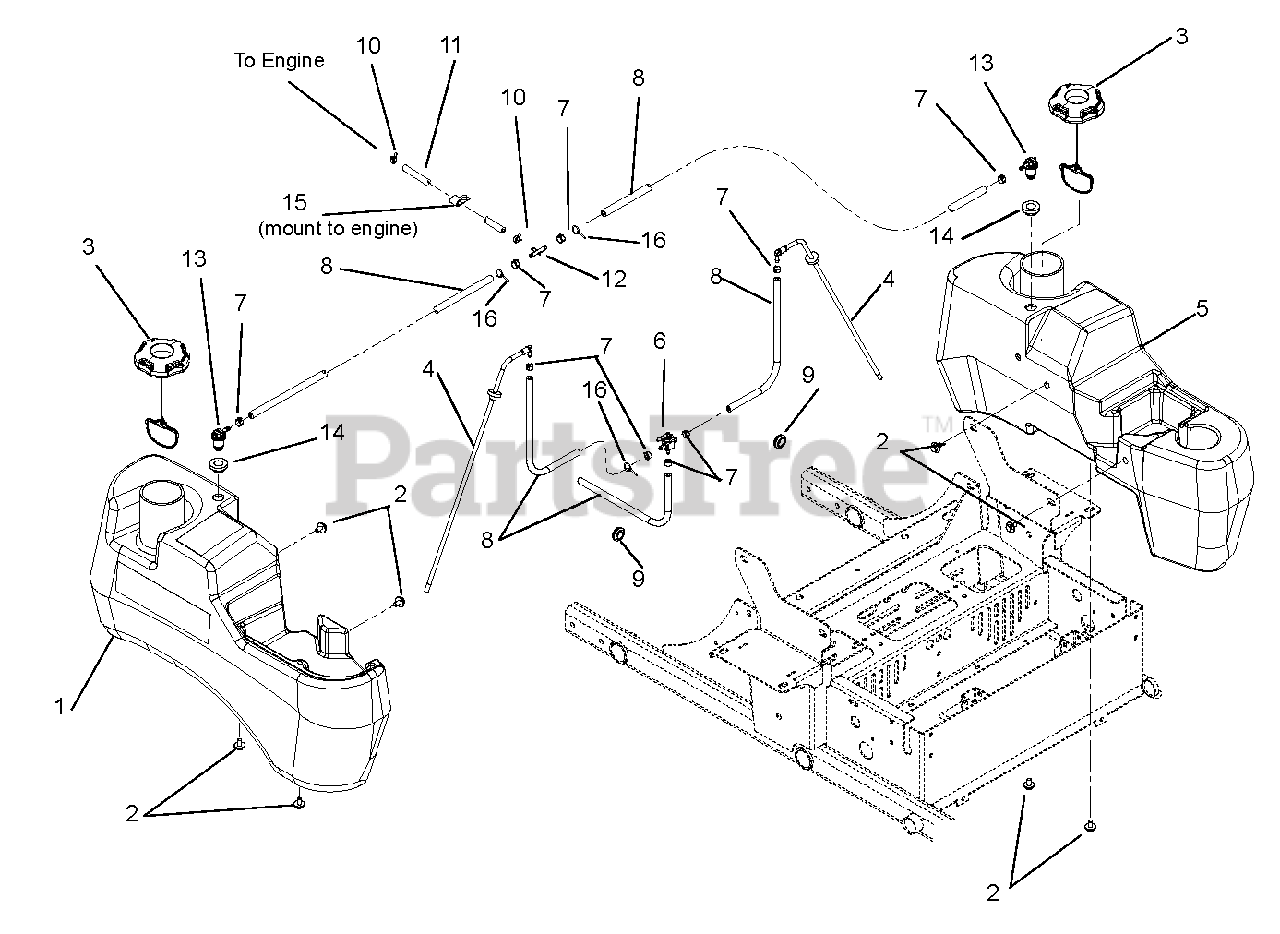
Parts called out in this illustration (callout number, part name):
1	Tank, Right Hand Fuel
2	Bolt, SEMS .31-18 x .62
3	Cap, Vent-In Autolock
4	Assembly, Large Tank Fuel Pick-Up
5	Tank, Left Hand Fuel
6	Valve, Fuel
7	Clamp, Fuel Line
8	Hose, .25 Low-Perm Bulk Gas
9	Grommet, Rubber 5/8 ID/1.13 OD
10	Clamp, Hose, Spring .188
11	Hose, .188 Low-PERM Bulk Gas
12	Tee, 1/4HS Run x 3/16HS Branch
13	Valve, Combination
14	Grommet, Remote Vent Nitrile
16	Cable Tie with Tree (.25 hole)
